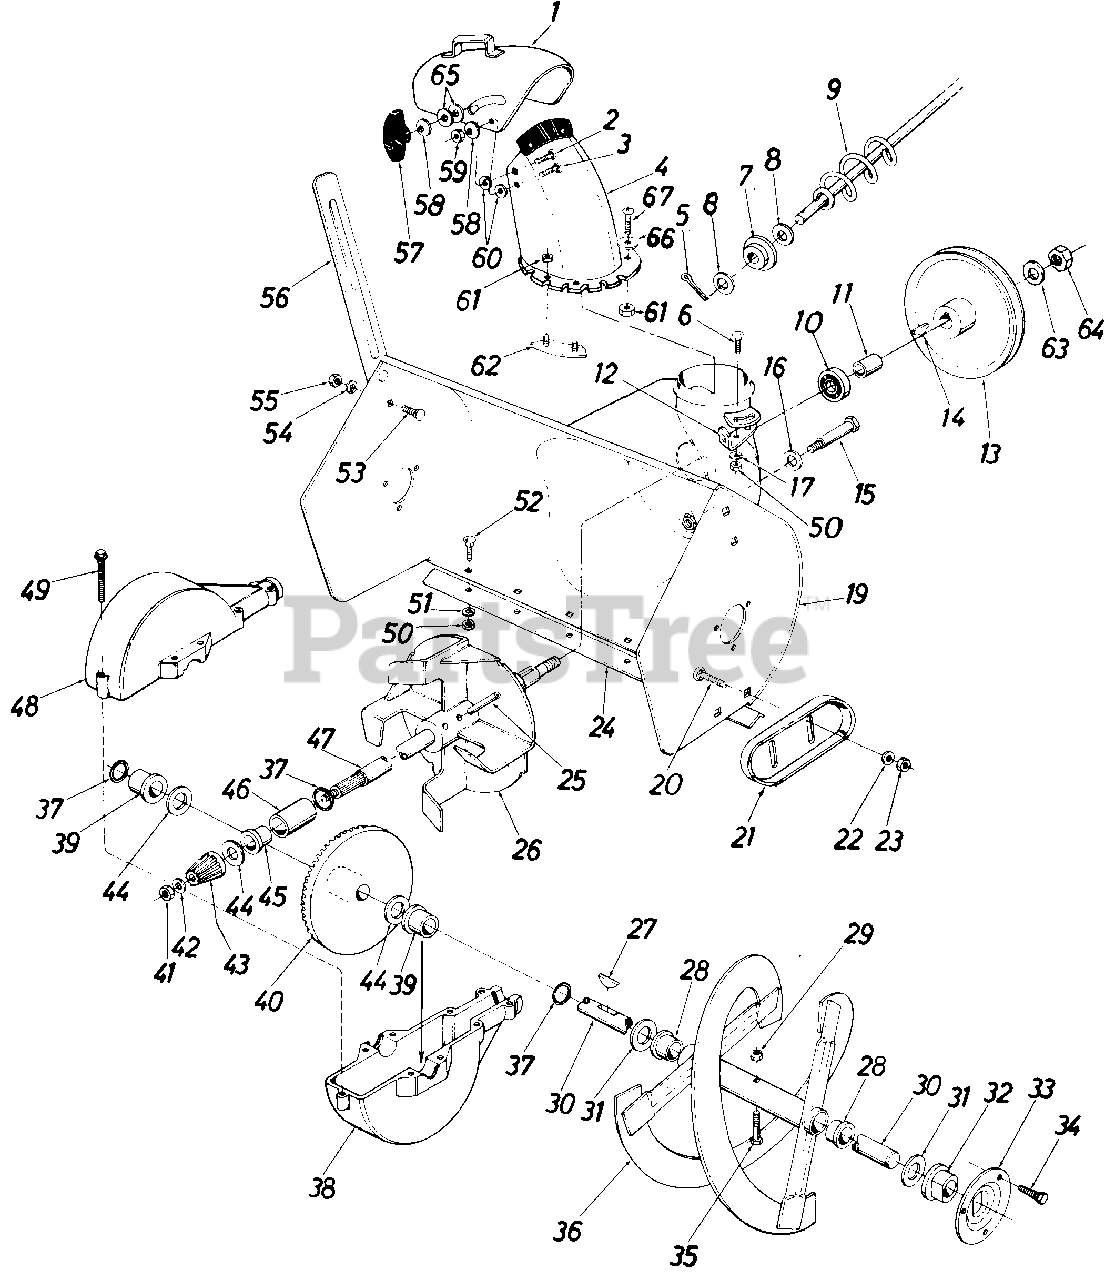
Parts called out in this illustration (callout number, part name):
1	Top Chute Ass'y.
2	Carriage Bolt 5/16-18 x 1.00" Lg.*
3	Carriage Bolt 5/16-18 x .62" Lg.*
4	Chute Ass'y.
5	Cotter Pin
6	Carriage Bolt 5/16-18 x .751" Lg. *
7	Hex Bushing
8	Fl-Wash. .385 I.D. x .62" O.D.
9	Chute Crank Ass'y.
10	Ball Brg. .62" I.D. x 1.38" 0. D
11	Space 63" I.D. x .88" O.D. x .900" Lg.
13	1/2" "V"-Pulley .625" I.D. x 7.50" O.D.
14	#61 Hi-Pro Key 3/16" x 5/8" Dia.
15	Shld. Bolt .50" Dia. x 2.11"
16	Bell-Wash. .40" I.D. x .88" O.D. x .06
17	Bell-Wash. .34" I.D. x .88" O.D.
19	24" Blower Housing Ass'y.
20	Carriage Bolt 3/8-16 x .62" Lg.*
21	Slide Shoe
22	Bell-Wash. 318" I.D.
23	Hex Jam Nut 3/8-16 Thd.
24	24" Shave Plate
25	Spring Pin Spiral 1/4" Dia. x 1.50" Lg.
26	11" Dia. Blower Fan Ass'y.
27	#9 Hi-Pro Key 3/16 x 3/4" Dia.
28	Flange Brg. .75" I.D. x .88" O.D. x .62
29	Hex Ins. L-Nut 5/16-18
30	Spiral Axle
31	Fl-Wash. .75" I.D. x 1.50" O.D. x .06
32	Flange Brg. w/Flats .755" I.D.
33	Bearing Housing
34	Hex Wash. Hd. Self-Tap Scr. 5/16-24 x .50" Lg.
35	Hex Bolt 5/16-18 x 1.50" Lg.
36	24" Spiral Ass'y.-L.H.
37	"O"-Ring-3/4" I.D.
38	Bevel Gear Housing-Lower Half
39	Plastic Flange Brg. .755" I.D.
40	Bevel Gear
41	Hex Cent. L-Nut 5/16-24 Thd.
42	Fl-Wash. .34" I.D. x .62" O.D. x .06
43	Pinion Gear
44	Fl-Wash. .75" I.D. x 1.25" O.D. x .06
45	Flange Brg. .755" I.D.
46	Sleeve Brg. .755" I.D.
47	Blower Axle
48	Bevel Gear Housing- Upper Half
49	Hex Wash. Hd. Self-Tap Scr. 1/4-20 x 1.00" Lg.
50	Hex Nut 5/16-18 Thd.*
51	Bell-Wash. .34" I.D. x .88" O.D.
52	Carriage Bolt 5/16-18 x .62" Lg.*
53	Carriage Bolt 5/16-18 x .62" Lg.*
54	L-Wash. 5/16" I.D.*
55	Hex Nut 5/16-18 Thd.*
56	Drift Cutter Bar
57	Knob
58	Bell-Wash. .34" I.D. x .88" O.D.
59	Hex Cent. L-Nut 5/16-18 Thd.
60	Fl-Wash. .53" I.D. x 1.25" O.D. x .100
61	Hex Cent. L-Nut 1/4-20 Thd.
62	Chute Flange Keeper Ass'y.
63	Fl-Wash. .64" I.D. x .94" O.D. x .06
64	Hex Jam Nut 5/8-18 Thd.
65	Fl-Wash. .344 I.D. x 1.125 O.D.
67	Hex Bolt 1/4-20 x .50"
